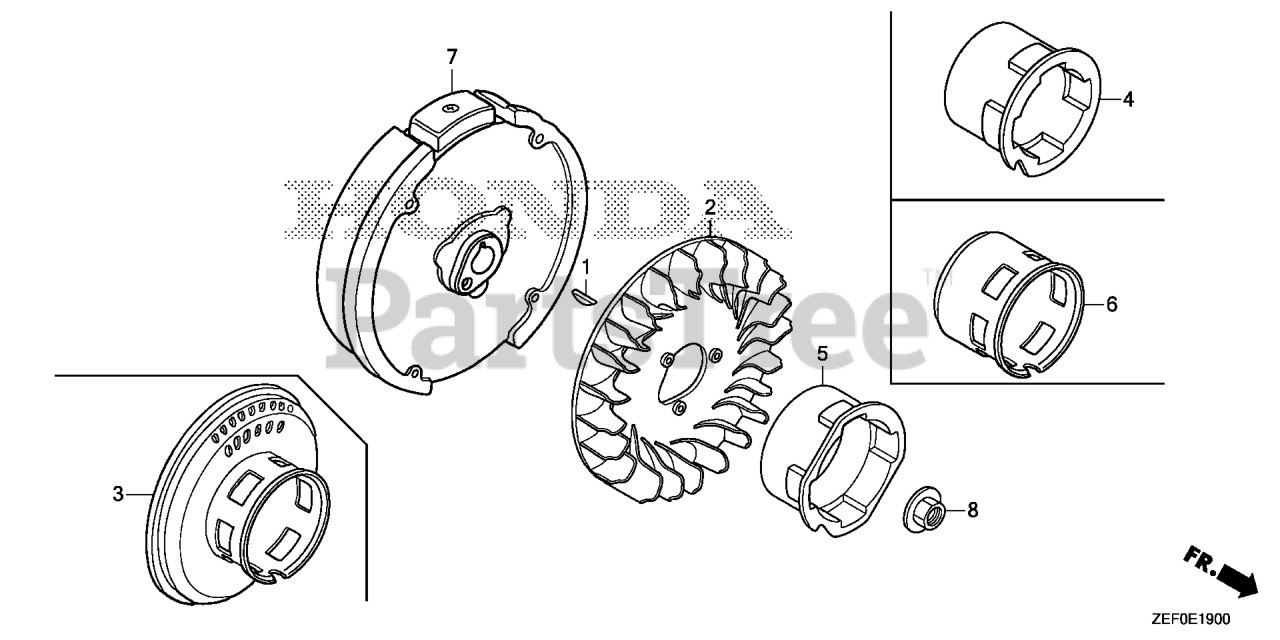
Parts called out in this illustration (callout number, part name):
1	KEY, SPECIAL WOODRUFF (25X18)
2	FAN, COOLING
5	PULLEY, STARTER
7	FLYWHEEL (STD)
8	NUT, SPECIAL (14MM)
